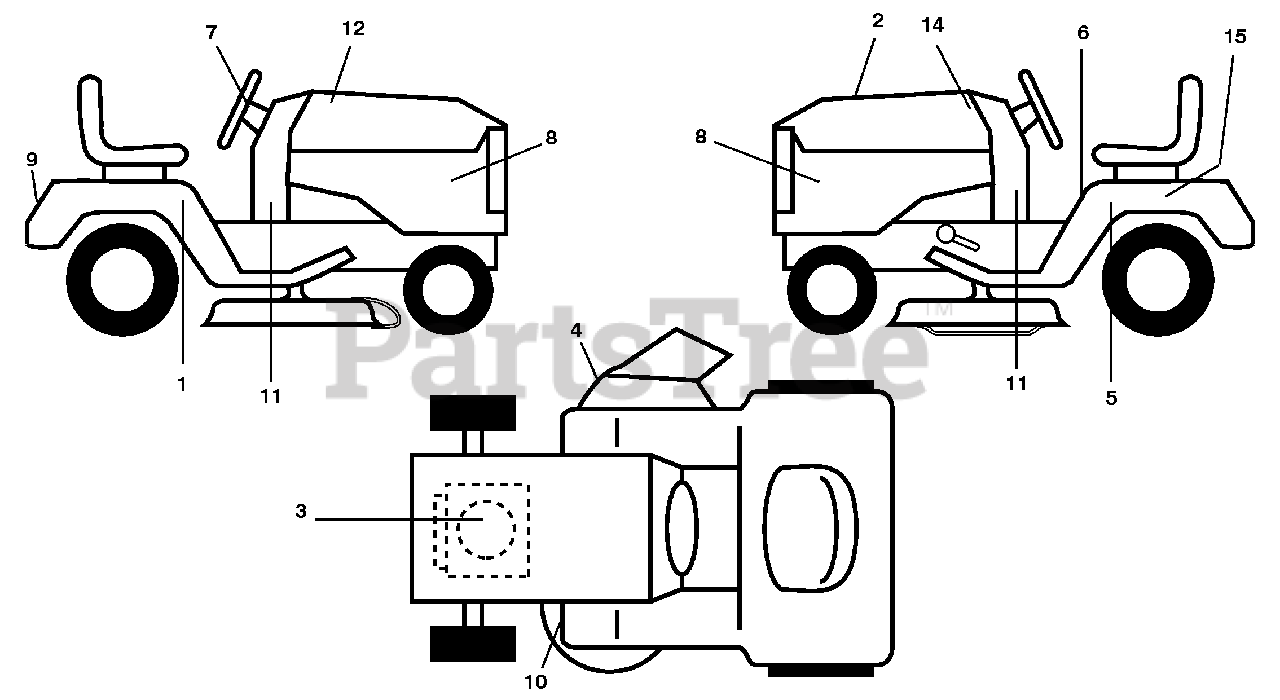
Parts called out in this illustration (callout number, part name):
1	Decal, Fender RH
2	Decal, Replacement
3	Decal, Engine HP
4	Decal Warning
5	Decal, Fender LH
6	Decal, Fender Danger Eng/Fr
7	Decal Ins Str Wh
8	Decal, Side Panel
9	Decal, Fender
10	Decal, V-Belt Sch.
11	Decal, Lower Dash
12	Decal, Hood RH
14	Decal, Hood LH
15	Decal, Caution, Battery
15	Decal, Bypass
15	Decal, Handle Lft Height Adj.
15	Pad Footrest LH
15	Pad Footrest RH
15	Manual, Operator's (E&F)
15	Manual, Parts (E&F)
